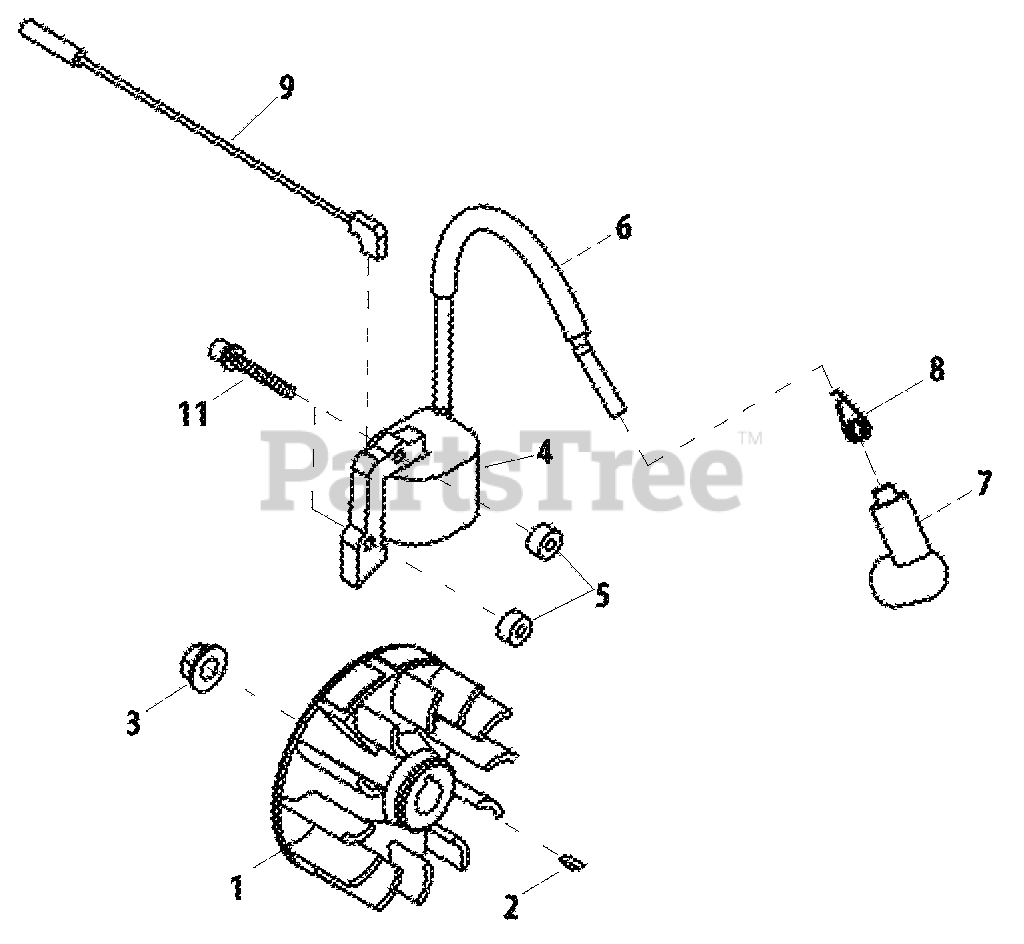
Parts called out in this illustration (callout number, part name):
1	FLYWHEEL
2	KEY, WOODRUFF 3×10
3	NUT M8
4	COIL, IGNITION
5	INSULATOR 4.2×11×6
6	TUBE
7	CAP, SPARK PLUG
8	TERMINAL, SPARK PLUG
9	LEAD - GROUND
11	BOLT M4×26
